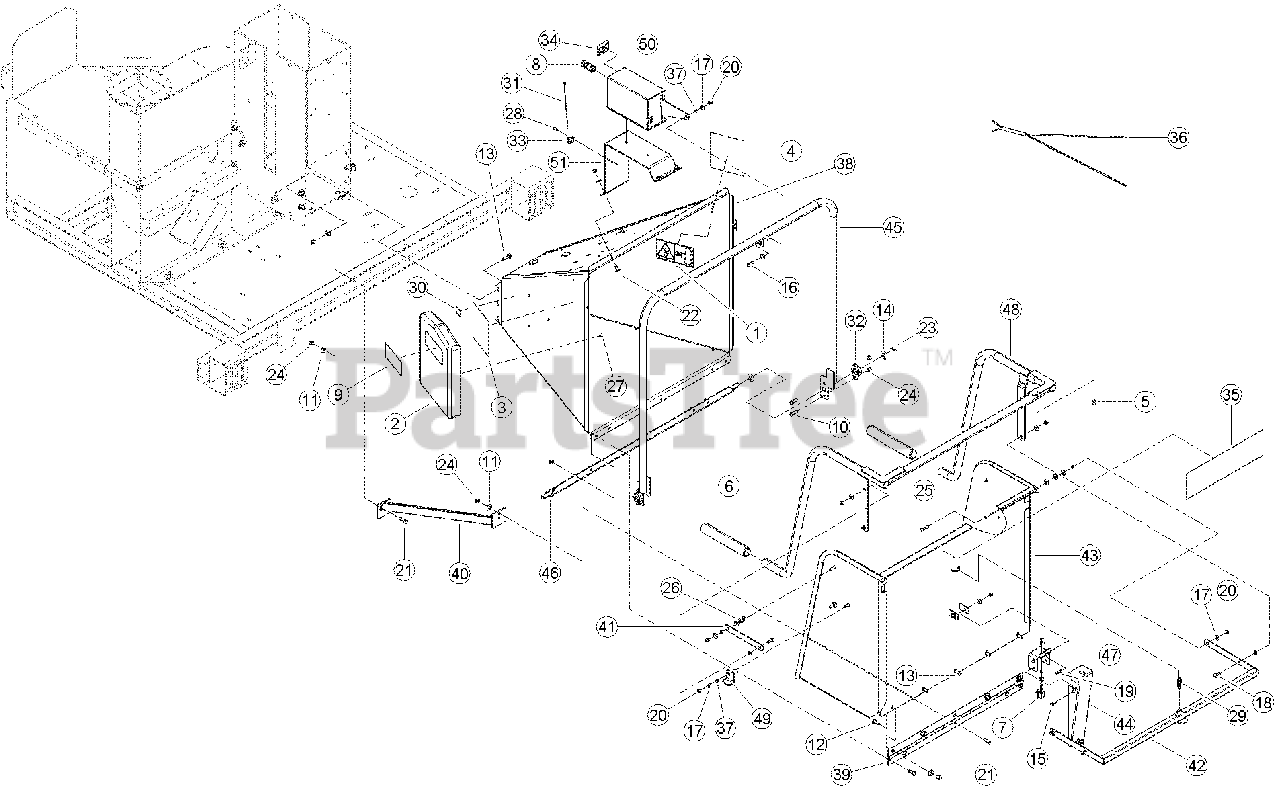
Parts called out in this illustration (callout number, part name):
1	DECAL, BLADE DANGER ISO
2	CONTAINER, INSTRUCTION MANUAL
3	DECAL, FEED POSITION
4	DECAL, FEED POSITION
5	BUMPER, RUBBER
6	GRIP, 1.219 X 10.00
9	DECAL, MUTILINGUAL MANUAL
10	BOLT, 3/8 X 1 HEX HD GR5 ZP
11	WASHER, 3/8 FLAT ZP
12	BOLT, 3/8 X 1 CRG GR5 NC ZP
13	BOLT, 3/8 X 1-1/2 CRG GR5 NC ZP
14	WASHER, 5/8 SAE FLAT ZP
15	SCREW, 11/32 X 7/8 HWH AB THREAD ZP
16	BOLT, 5/16 X 1 HHCS GR5 NC ZP
17	WASHER, 5/16 FLAT ZP
18	BOLT, 5/16 X 1 CRG GR5 ZP
19	BOLT, 5/16 X 7/8 CRG GR5 NC ZP
20	NUT, 5/16 NE NYLOCK ZP
21	BOLT, 3/8 X 1-1/4 HEX HD GR5 ZP
22	BOLT, 5/16 X 3/4 CRG GR5 NC ZP
23	PIN, 1/8 X 1.00 ZP COTTER
24	NUT, 3/8 NE NYLOCK ZP
25	BOLT, 5/16 X 1-1/4 CRG GR5 ZP
26	WASHER, 5/16 ID. X 7/8 OD. NYLON FLAT
27	RIVET, AL BLIND 1/4 X 1/2 DOME HEAD
28	RIVET, AL BLIND 1/4 X 3/4 DOME HEAD
29	SPRING 1/2 X 2.00 LG,ZP
30	DECAL, CE APPROVAL
31	STRAP, 11 IN. BLACK TIE
32	BEARING, SIDE FLANGE MOUNT, 5/8
33	CLAMP, CABLE MOUNT
34	DECAL, RESET/OVERRIDE
35	HARNESS, SAFETY BAR
36	SPACER, IDLER PIVOT
37	WELDMENT, BIG CHIPPER CHUTE
38	HINGE, EXTENSION TRAY
39	WELDMENT, CHUTE SUPPORT
40	LINK, PARALLEL
41	WELDMENT, KNEEBAR PIVOT
43	SHIELD, KNEEBAR SWITCH
44	WELDMENT, CONTROL ARM
45	WELDMENT, CONTROL PIVOT
46	BRACKET, SWITCH
47	WELDMENT, KNEEBAR
48	LOCK, SAFETY BAR
49	ASSEMBLY, SWITCH BOX
50	MOUNT, SWITCH BOX
